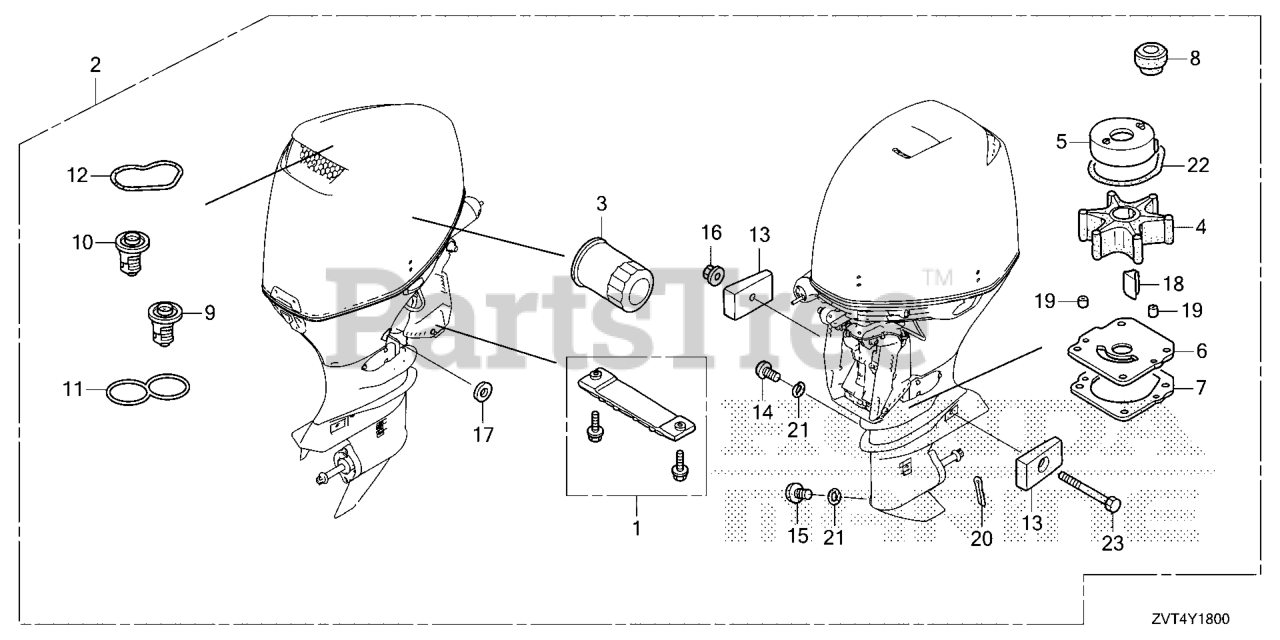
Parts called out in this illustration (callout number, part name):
1	METAL KIT, ANODE Use from Frame SN 4800343.
2	KIT (200)
3	FILTER, OIL
4	IMPELLER, PUMP
5	LINER, PUMP
6	COVER, IMPELLER
7	GASKET B, IMPELLER
8	RING, WATER TUBE SEAL
9	THERMOSTAT ASSY.
10	THERMOSTAT ASSY.
11	GASKET, THERMOSTAT COVER
12	GASKET, THERMOSTAT SPACER
13	METAL, ANODE
14	BOLT, OIL CHECK
15	BOLT, DRAIN PLUG
16	NUT, SELF-LOCK (6MM)
17	WASHER, DRAIN PLUG (12MM)
18	KEY, WOODRUFF
19	PIN, DOWEL (6X10)
20	PIN, SPLIT (4.0)
21	O-RING (6.9X1.45)
22	O-RING, WATER PUMP
23	BOLT, HEX. (6X50)
